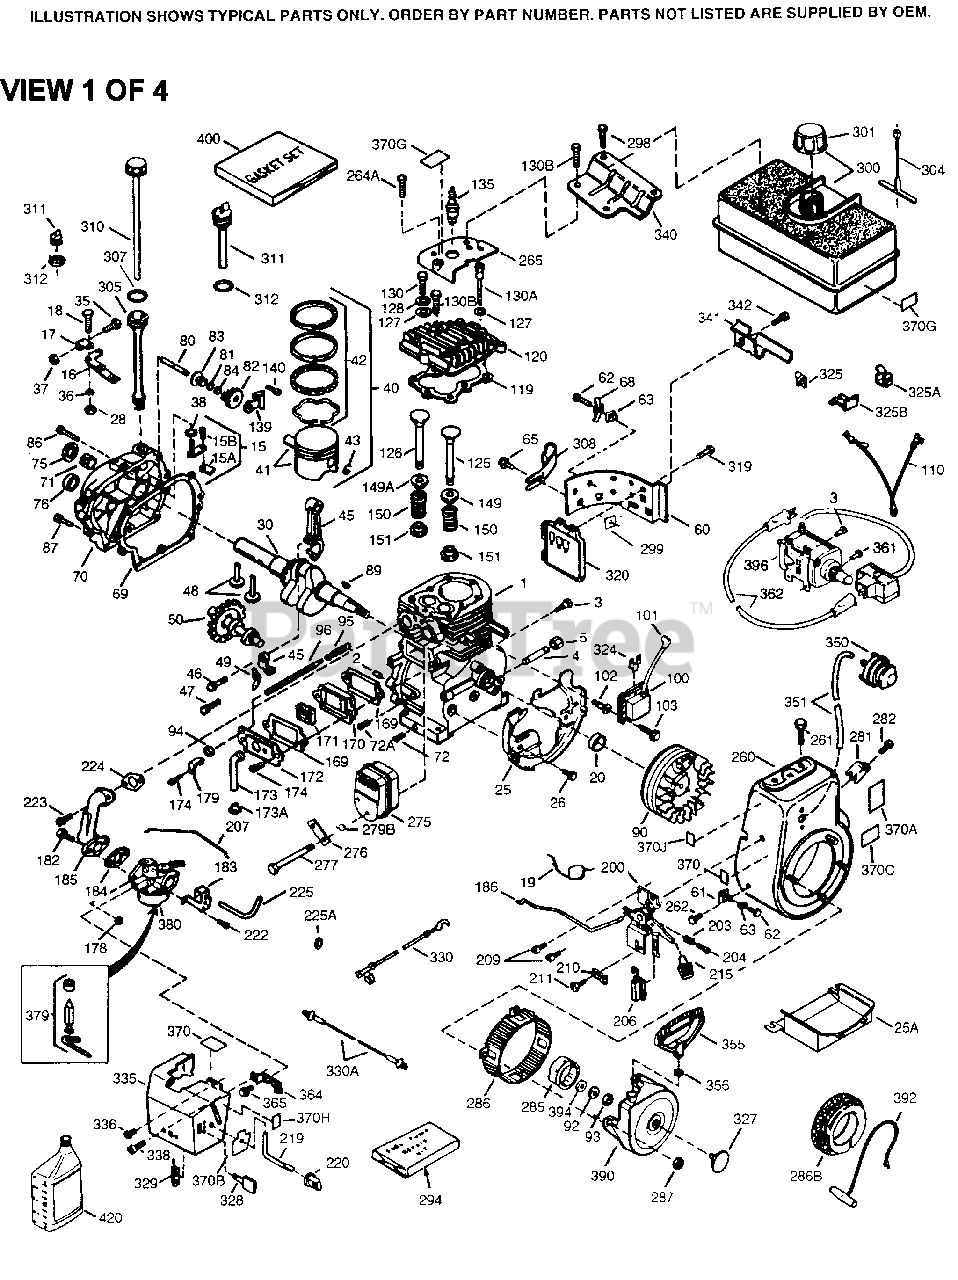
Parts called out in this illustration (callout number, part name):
1	"Cylinder Ass'y. (Incl. 2, 20, 72 & 72 A)(3-1/8" Bore)
2	Dowel Pin
4	Oil Drain Extension
5	Extension Cap
15	Governor Rod (Incl. 15A & 15B)
15A	Governor Yoke
15B	Screw, 6-40 x 5/16"
16	Governor Lever
17	Governor Lever Clamp
18	Screw, Torx T-15, 8-32 x 3/8"
19	Speed Control Spring
20	Oil Seal
25	Blower Housing Baffle
26	Screw, 1/4-20 x 5/8"
28	Lock Nut, 8-32
30	Crankshaft
35	Screw, 10-32 x 3/4"
36	Lock Washer #8
37	Lock Nut, 10-32
38	Retaining Ring
40	Piston, Pin & Ring Set (Std.)
40	Piston, Pin & Ring Set (.010" OS)
40	Piston, Pin & Ring Set (.020" OS)
41	Piston & Pin Ass'y. (Std.) (Incl. 43)
41	Piston & Pin Ass'y. (.010" OS) Incl. 43
41	Piston & Pin Ass'y. (.020" OS) Incl. 43
42	Ring Set (Std.)
42	Ring Set (.010" OS)
42	Ring Set (.020" OS)
43	Piston Pin Retaining Ring
45	Connecting Rod Ass'y. (Incl.47 & 49)
47	Connecting Rod Bolt
48	Valve Lifter
49	Oil Dipper
50	Camshaft (MCR)
60	Blower Housing Extension
65	Screw, 10-24 x 1/2"
69	* Cylinder Cover Gasket
70	Cylinder Cover (Incl. 71, 75 & 80)
71	Crankshaft Bushing
72	Oil Drain Plug (Sq. hd., 1/4-18)
75	Oil Seal
76	Camshaft Seal
80	Governor Shaft
82	Governor Gear Ass'y. (Incl. 81)
83	Governor Spool
84	Retaining Ring
86	Screw, 1/4-20 x 1-3/16"
87	Screw, 1/4-20 x 1-11/16"
89	Flywheel Key
90	Flywheel
92	Lock Washer
93	Flywheel Nut
100	Solid State Ignition
101	Spark Plug Cover
102	Solid State Mounting Stud
103	Screw, Torx T-15, 10-24 x 15/16"
110	Ground Wire
119	* Cylinder Head Gasket
120	Cylinder Head
125	Exhaust Valve (Std.)(Incl. 151)
125	Exhaust Valve (1/32" OS) (Incl. 151)
126	Intake Valve (Std.) (Incl. 151)
126	Intake Valve (1/32" OS) (Incl. 151)
128	Belleville Washer
130	Screw, 5/16-18 x 2"
131A	Screw, 1/4-20 x 5/8"
135	Resistor Spark Plug - RJ17LM
139	Governor Gear Bracket
140	Screw, 10-24 x 1/2"
149	Valve Spring Cap
149A	Valve Spring Cap
150	Valve Spring
151	Valve Spring Keeper
169	* Valve Cover Gasket
170	Breather Body
171	Breather Element
172	Valve Cover
173	Breather Tube
174	Screw, 10-24 x 1/2"
178	Nut & Lock Washer 1/4-28
182	Screw, 1/4-28 x 1"
184	* Carburetor To Intake Pipe Gasket
185	Intake Pipe
186	Governor Link
200	Control Bracket (Incl. 203 & 204)
203	Compression Spring
204	Screw, Torx T-10, 5-40 x 7/16"
206	Terminal
207	Throttle Link
209	Screw, 10-32 x 1/2"
215	Control Knob
223	Screw, Torx T-30, 5/16-18 x 1-1/8"
224	* Intake Pipe Gasket
260	Blower Housing
261	Screw, 5/16-18 x 3/4"
262	Screw, T-40, 5/16-24 x 21/32"
264A	Screw, 1/4-20 x 5/8"
265	Cylinder Head Cover
275	Muffler
276	Locking Plate
277	Screw, 5/16-18 x 3-3/16"
277A	Screw, 5/16-18 x 3-31/32"
280	Heat Shield
281	Starter Bubble Cover
282	Screw, 8-32 x 3/8"
285	Starter Cup
287	Nut & Lock Washer 1/4-28
305	Oil Fill Tube
307	"O" Ring
308	Fill Tube Clip
310	Dipstick
325	Wire Clip
327	Starter Plug
342	Screw, T-30, 1/4-20 x 1/2"
370	Name Decal
370G	Decal - Important Lubrication - SAE 3
370J	Speed Control Decal
380	Carburetor (Incl. 184)
390	Rewind Starter
400	* Gasket Set (Incl. items marked PK in notes) Incl. part #'s 27272A (1),2789 6A (2), 27915A (1), 29673 (1),33263 ( 1), 33629 (1), 34698A (1),35262 (1), 36448 (1)
900	Rep. Engine 756310A, Order From 71-99 9
900	Rep. Short Block - None
